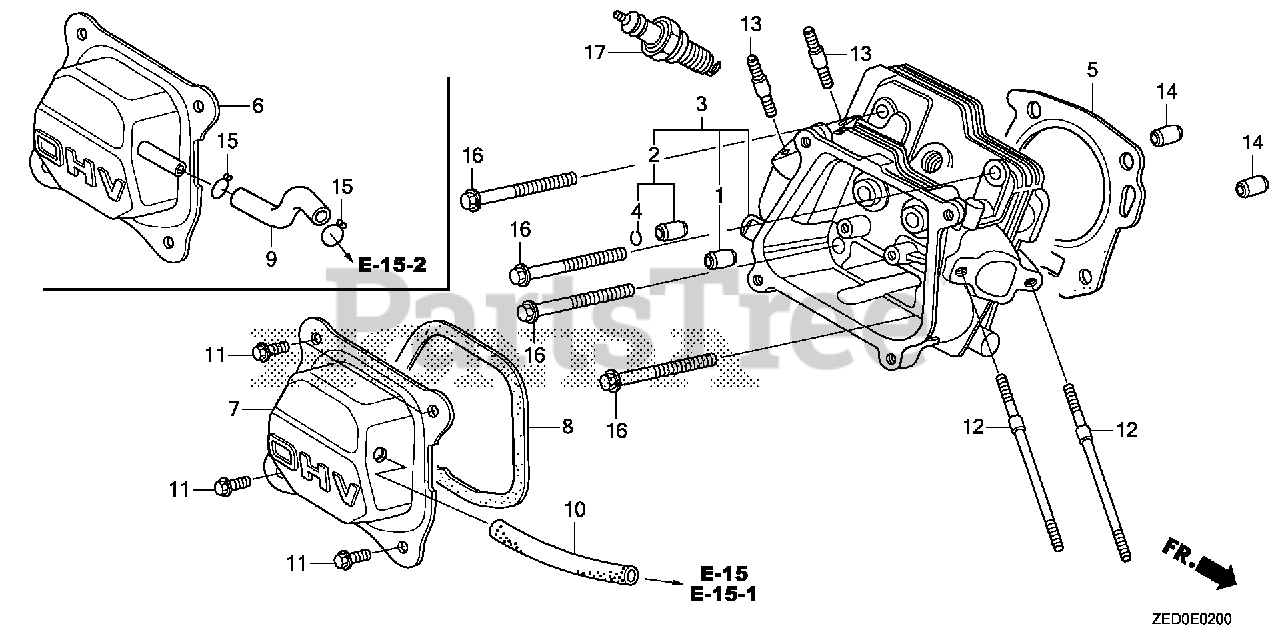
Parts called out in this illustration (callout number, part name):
1	GUIDE, VALVE (OVER SIZE) Use from Engine SN 6324986.
2	GUIDE, EX. VALVE (OS)
3	CYLINDER HEAD
4	CLIP, VALVE GUIDE Use from Engine SN 1231803.
5	GASKET, CYLINDER HEAD (NIPPON LEAKLESS)
7	COVER, HEAD
8	GASKET, HEAD COVER (NINGBO SIL GASKET)
8	GASKET, CYLINDER HEAD COVER
10	TUBE, BREATHER
11	BOLT, FLANGE (6X12) (CT200)
12	BOLT, STUD (6X112)
13	BOLT, STUD (8X32)
14	PIN A, DOWEL (10X16)
16	BOLT, FLANGE (8X60)
17	SPARK PLUG (BPR5ES) (NGK)
17	SPARK PLUG (W16EPR-U) (DENSO)
17	SPARK PLUG (BPR6ES) (NGK)
17	SPARK PLUG (W20EPR-U) (DENSO)
